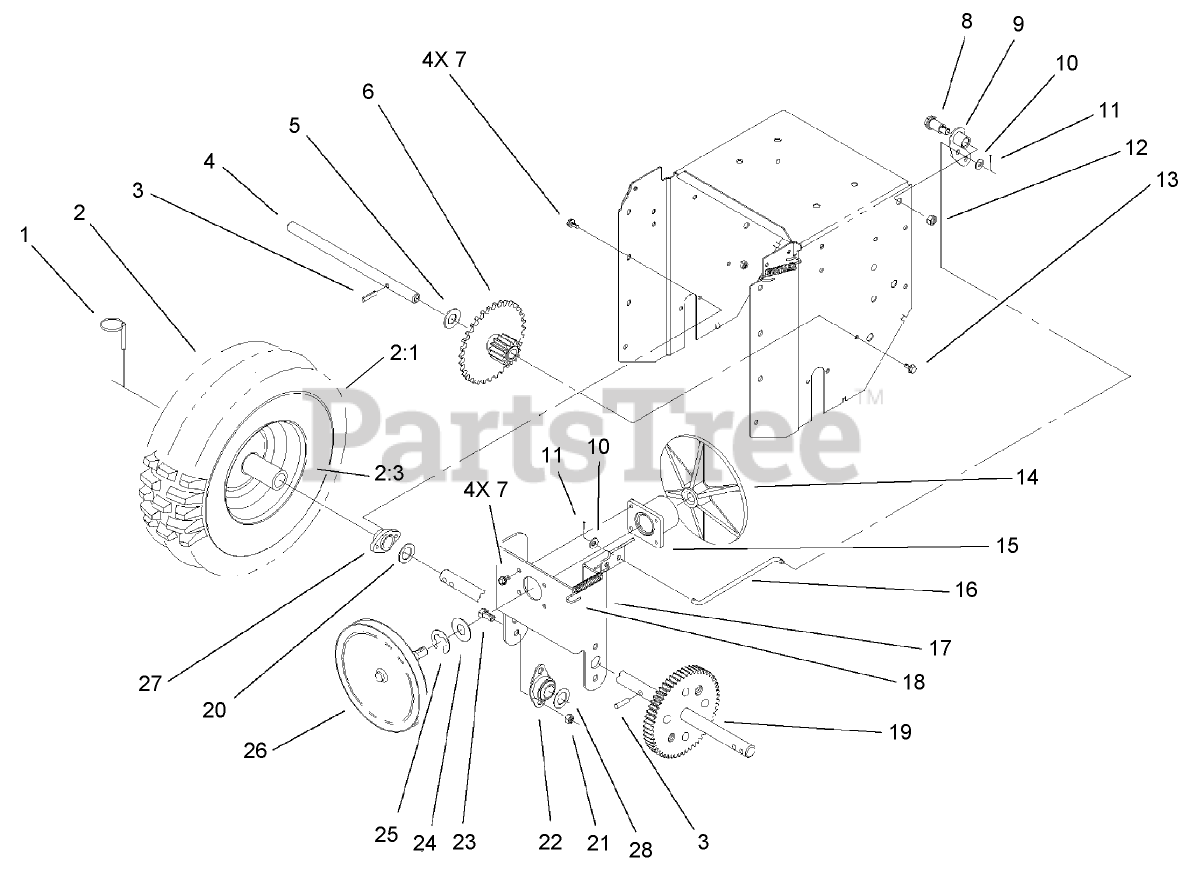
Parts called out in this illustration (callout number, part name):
1	PIN-LYNCH
2	ORDER SEPERATE COMPONENTS
2:3	RIM-WHEEL
3	PIN-ROLL, SLOTTED
4	SHAFT - INTERMEDIATE
5	WASHER
6	GEAR/BUSHING ASM
7	SCREW-HWH
8	BOLT - SHOULDER
9	HUB-PIVOT
10	WASHER
11	PIN-COTTER
13	SCREW-HWHTF
14	DISC - FRICTION
16	ROD - ENGAGE
17	FRAME-FRICTION PLATE
20	WASHER-THRUST
21	NUT-LOCK, NI
22	BUSHING
23	SCREW-HH
24	WASHER-THRUST
25	RING-RETAINING, EXT
26	PULLEY/SHAFT ASM
27	BEARING-AXLE
28	WASHER-THRUST
